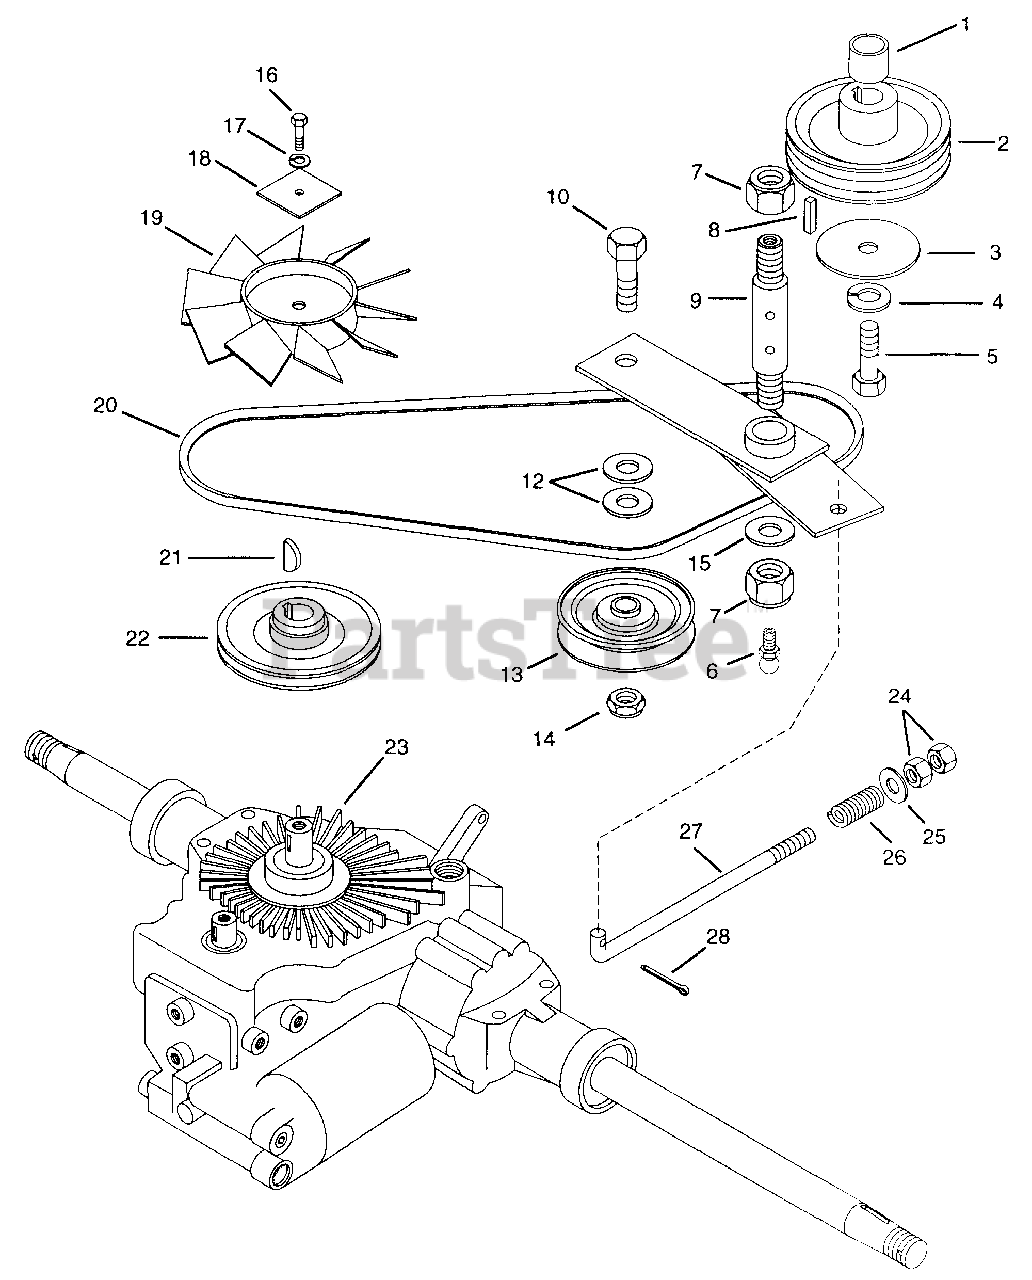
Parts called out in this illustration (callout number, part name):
1	Bushing, Sleeve 1.00 x 1.25 x 1.25 (007)
1	Bushing, Sleeve 1.13 x 1.38 x 1.25 (008,011)
2	Sheave (007)
2	Sheave (008)
2	Sheave (011)
3	Washer-Special .469 x 2.000 x .250
4	Washer-Lock .44
5	Bolt-Hex .44-20 x 1.50 Grade 5
6	Fitting, Lube 1/8
7	Nut-Locking 5/8-11
8	Key-Square .248 x 1.25 x .248
9	Pin, Pivot
10	Bolt-Hex .50-13 x 1.625
11	Weldment, Idler Arm
12	Washer-Flat-Steel .531 x 1.062 x .095
13	Pulley-V 4.00 x .84
14	Nut-Locking .50-13
15	Washer-Flat-Steel .656 x 1.250 x .100
16	Bolt-Hex .25-20 x 1.25 Grade 5
17	Washer-Lock .250
18	Washer-Flat-Steel .265 x 1.75 Square x .119
19	Fan
20	V-Belt A-Section 18.05 x .495
21	Key, Woodruff .19 x .63
22	Pulley, Drive
23	Transaxle, Eaton #851-109
24	Nut-Hex .375-16
25	Washer-Flat-Steel .406 x .812 x .065
26	Spring-Compression .072 x .561 x 2.50
27	Rod, Idler
28	Pin-Cotter .09 x .75
